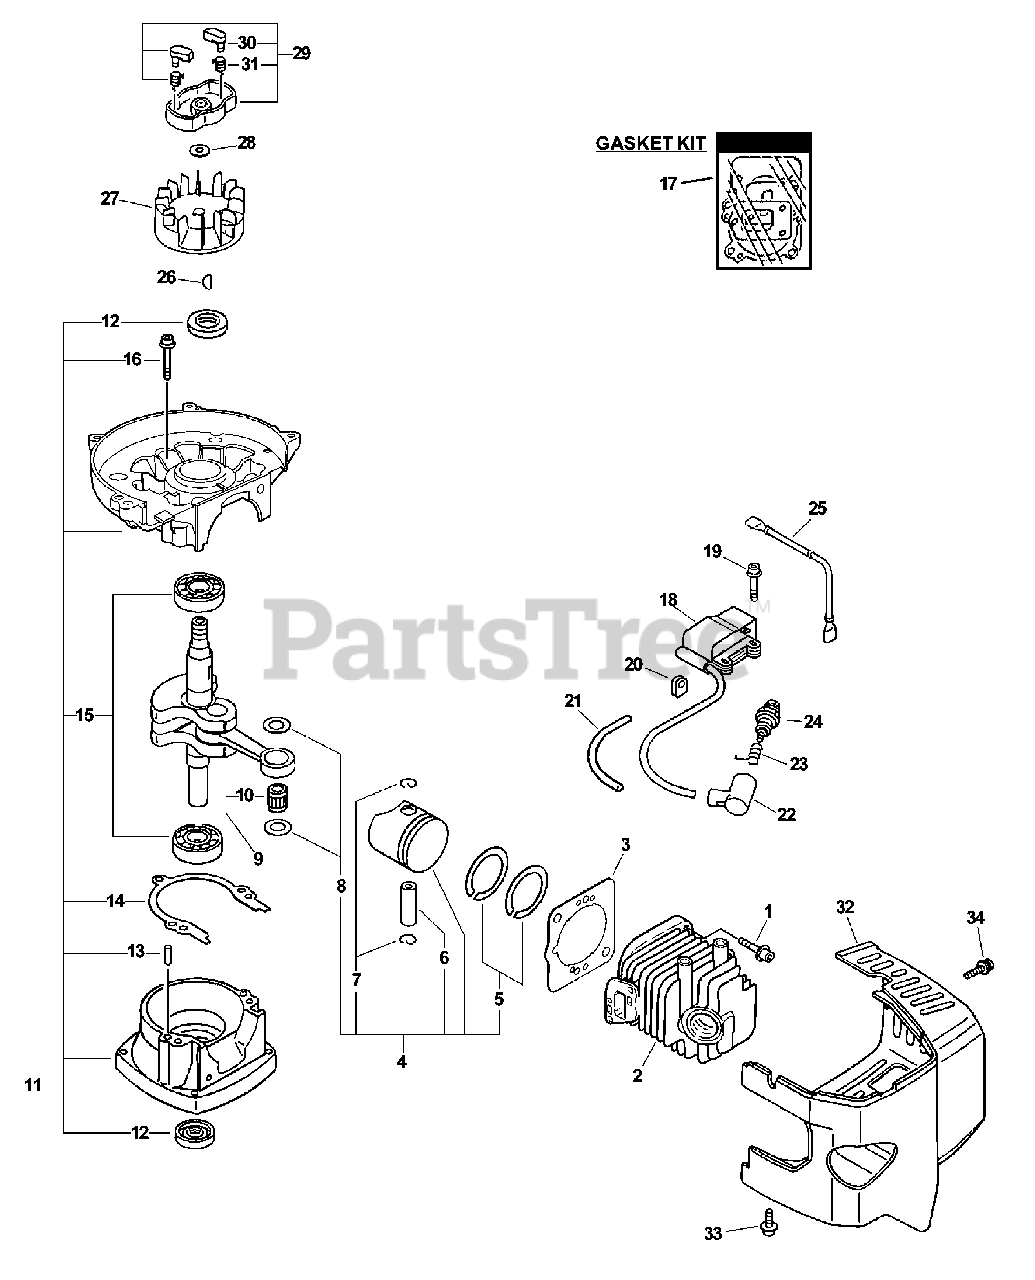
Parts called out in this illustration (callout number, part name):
1	SCREW - 5X22
2	CYLINDER
3	GASKET, CYLINDER
4	PISTON KIT
5	RING, PISTON
6	PIN, PISTON
7	RING, RETAINING
8	SPACER, PISTON
9	CRANKSHAFT ASSY
10	BEARING, NEEDLE - 8
11	CRANKCASE KIT
12	SEAL, OIL
13	PIN - LOCATING
14	GASKET, CRANKCASE
15	BEARING, BALL - 6201
16	SCREW - 5X28
17	GASKET KIT
18	COIL, IGNITION
19	SCREW - 4X20
21	TUBE, INSULATOR
22	CAP, SPARK PLUG
23	TERMINAL, SPARK PLUG CAP
24	SPARK PLUG -- BPMR-7A
25	LEAD - IGNITION
27	FLYWHEEL
28	LOCKWASHER - 8
29	STARTER PAWL ASSY
30	PAWL, STARTER - BLACK
31	SPRING, RETURN
32	COVER, ENGINE
33	SCREW - 4X18
34	SCREW - 4X8
